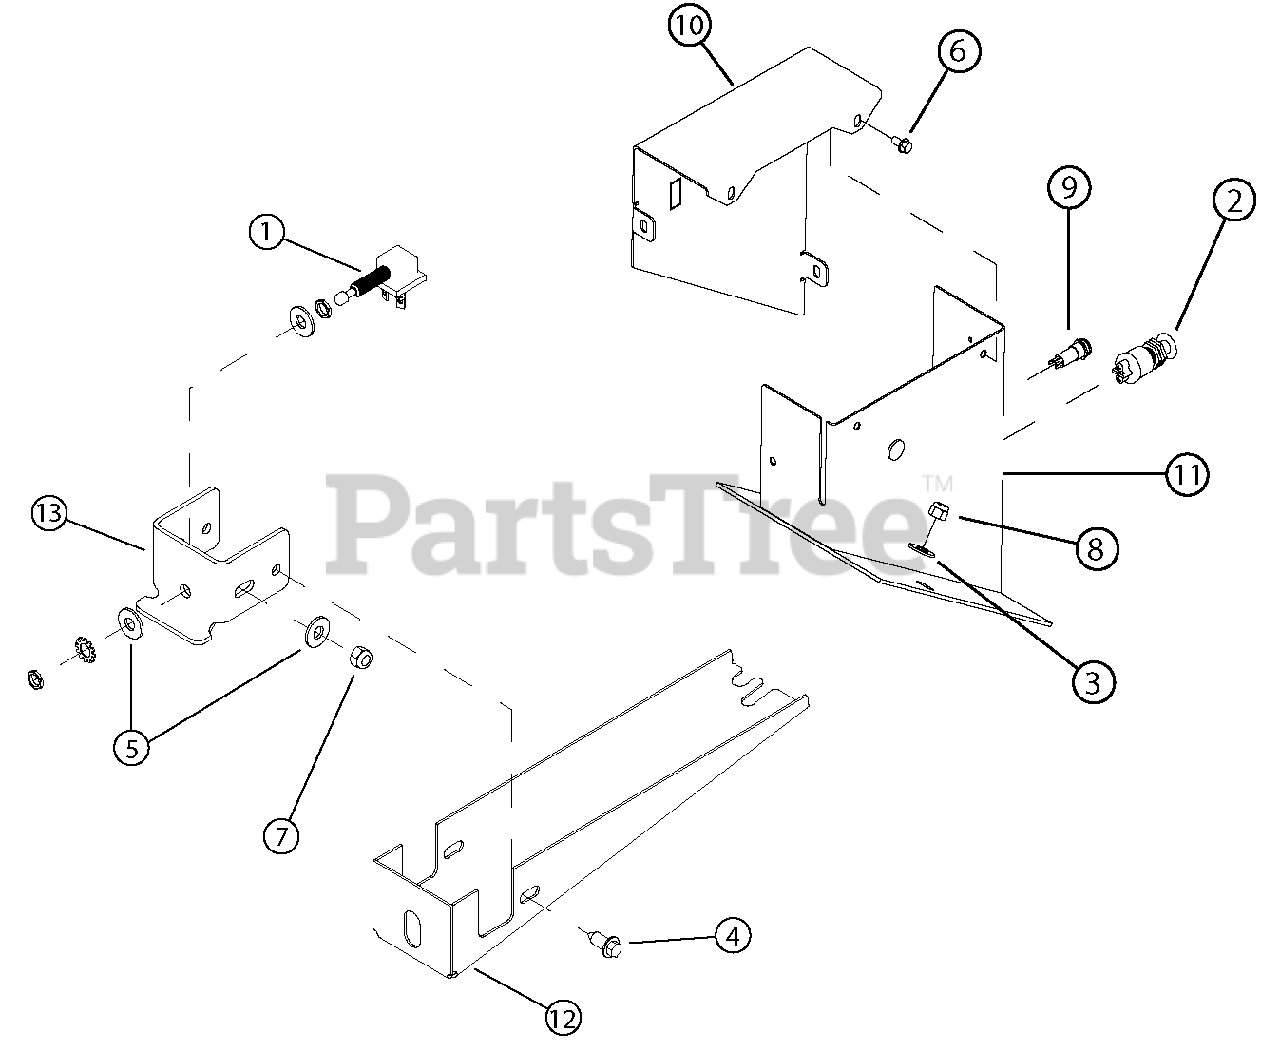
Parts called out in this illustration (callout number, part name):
1	SWITCH, N/C MOMENTATY PLUNGER
2	SWITCH, N/O MOMENTARY PUSHBUTTON
3	WASHER, 3/8 FLAT
4	SCREW, 11/32 X 7/8 HWH AB THREAD
5	WASHER, 5/16 FLAT
6	BOLT, SERR. FLANGE 1/4 X 1/2
7	NUT, 5/16 NYLOCK
8	NUT, 3/8 NYLOCK
9	LED, TRI-COLOR 12V 3-TERM BASE
10	PLATE, CONTROL BOX
11	WELDMENT, SWITCH MOUNT
12	SHIELD, KNEEBAR SWITCH
13	BRACKET, SWITCH
